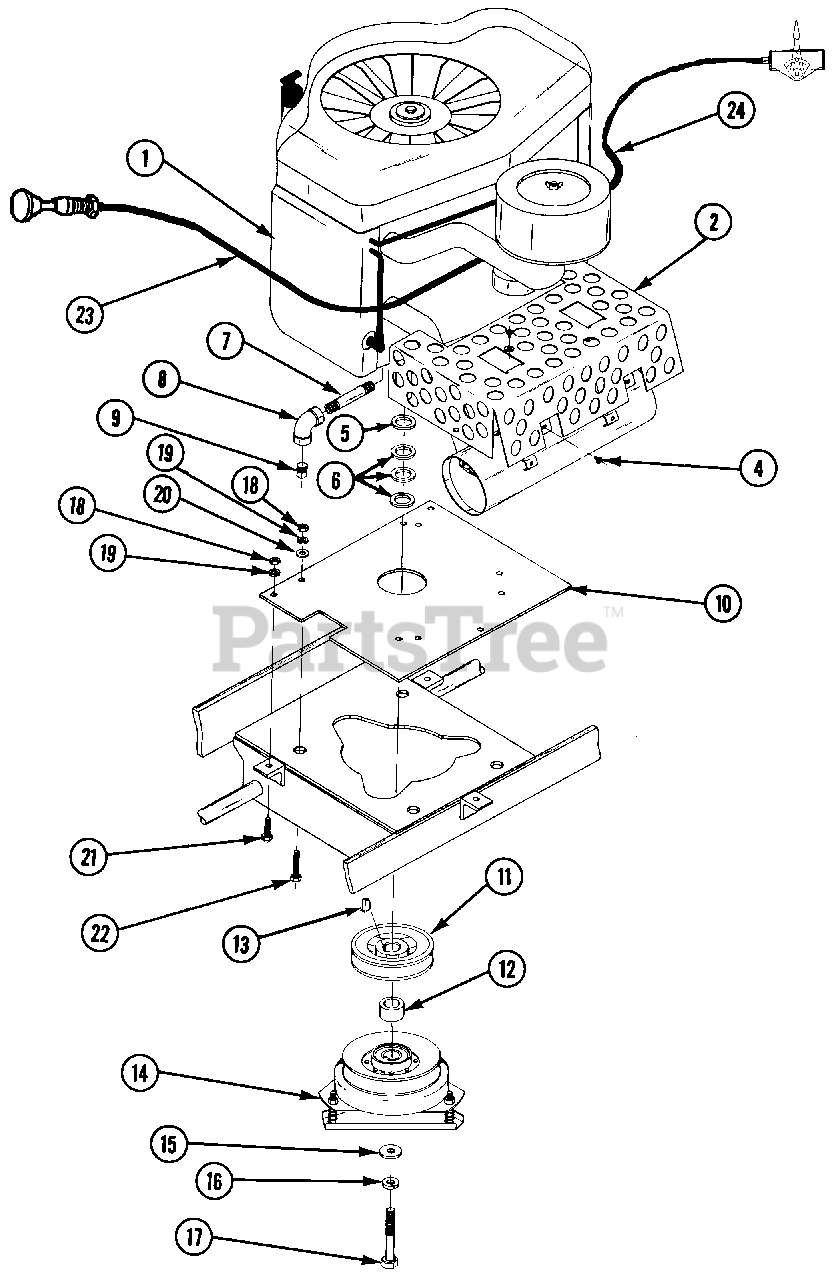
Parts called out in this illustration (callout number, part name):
2	MUFFLER GUARD
4	SCREW, #8 X 1/2 SHEET METAL MUFFLER GUARD
5	WASHER, 1-1/2 OD X 1-1/8 ID X 1/16 THK
6	WASHER, 1-1/2 OD X 1-1/8 ID X 1/8 THK
7	NIPPLE, 3/8 X 4, SCH. 40, BLACK
8	ELBOWS 3/8, 90 DEGREE, SCH. 40
9	3/8 PIPE PLUG
10	MOTOR MOUNTING PLATE
11	PULLEY BK50 1-1/8 ID 4" A PITCH
12	SPACER, PULLEY/ELECTRIC CLUTCH
13	KEY, WOODRUFF 1/4 X 3/4
14	CLUTCH, ELECTRIC #5210-17
15	WASHER, 15/32" ID
16	LOCKWASHER, 7/16 SPLIT SPRING
17	CAPSCREW, 7/16-20 X 3, GRADE 5
18	NUT, 5/16-24 UN, GRADE 5
19	LOCKWASHER, 5/16 HEAVY SPRING
20	WASHER, FLATS STD, STEEL, 5/16"
21	CAPSCREW, HEX, 5/16-24 X 1, GRADE 5
22	CAPSCREW, HEX, 5/16-24 X 1-1/2, GRADE 5
23	CHOKE CABLE
24	THROTTLE CABLE
